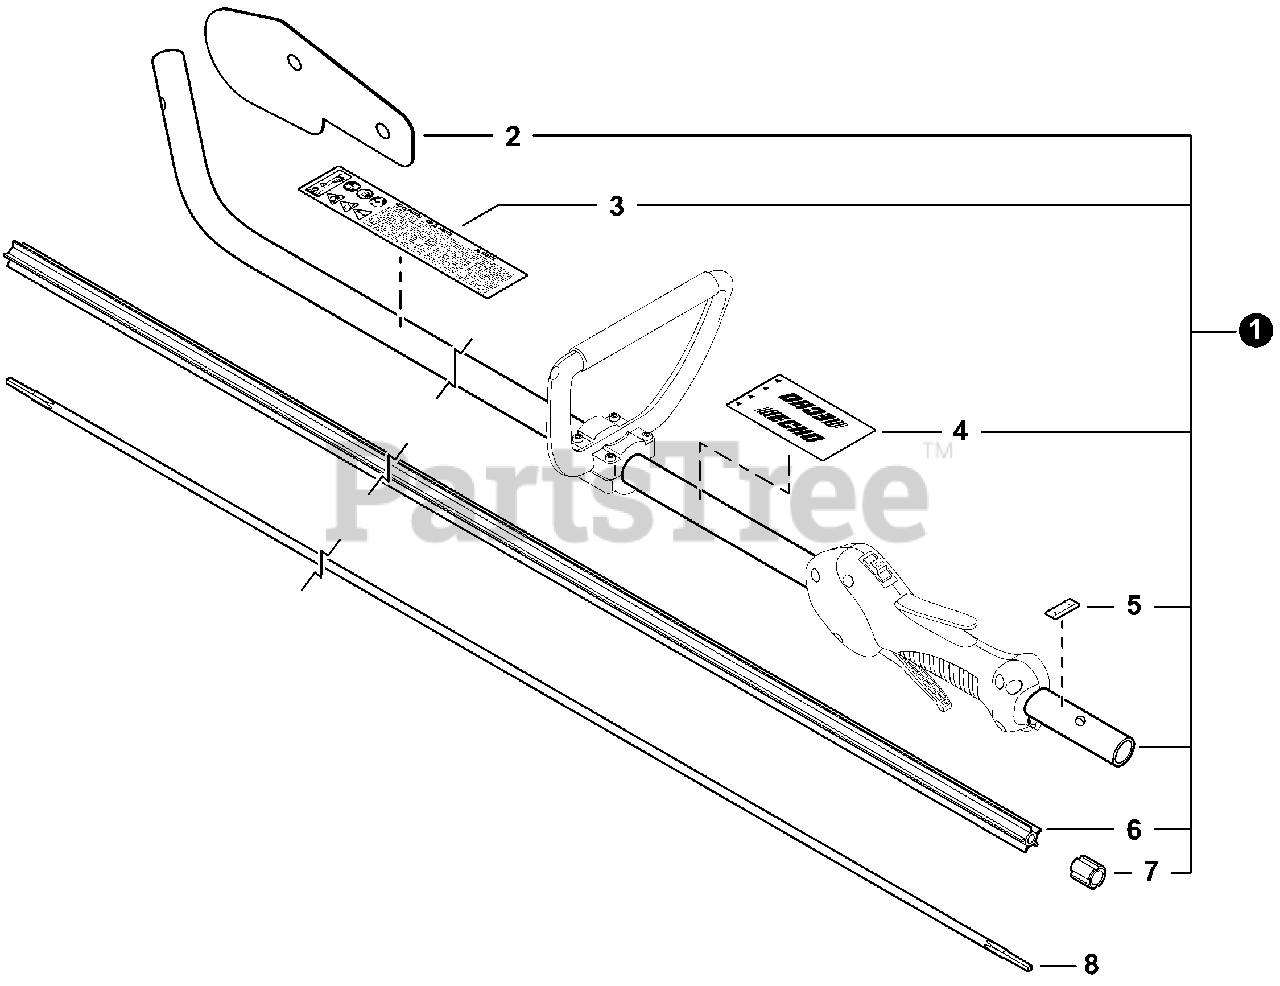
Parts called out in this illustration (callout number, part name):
1	MAIN PIPE KIT
2	PLATE, SHIELD
3	LABEL, CAUTION
4	LABEL, HANDLE LOCATION
5	LABEL - ALIGNMENT
6	LINER, FLEXIBLE 21.6×1420
8	DRIVESHAFT - FLEXIBLE
